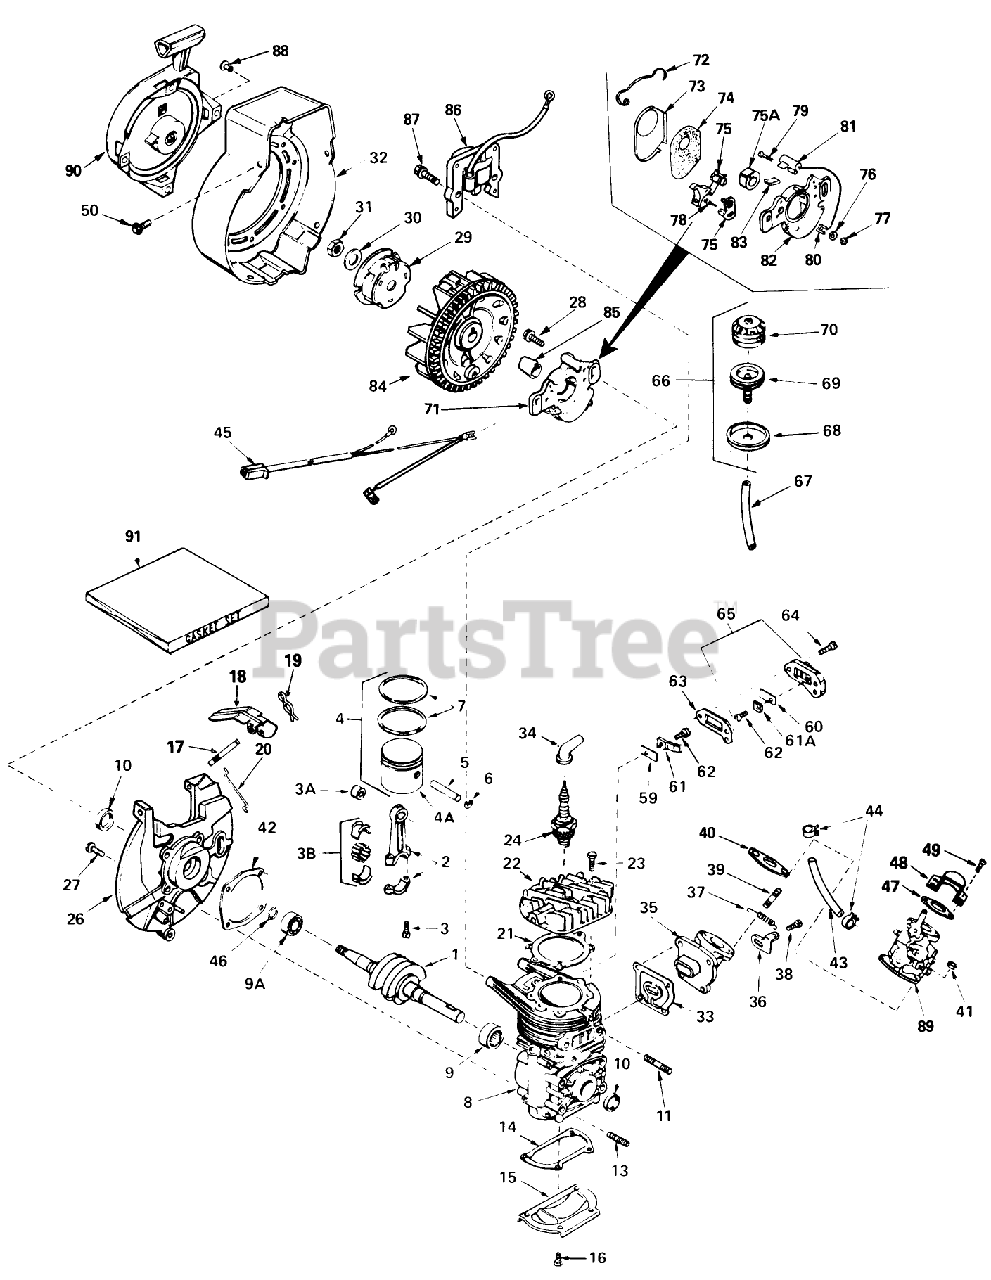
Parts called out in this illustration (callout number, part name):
1	Crankshaft
2	Rod Assembly, Connecting (Incl. #3, 3A 3B)
3	Bolt-Rod, Connecting
3A	Bearing-Cartridge
3B	Bearing Liner Set Needle
4	Piston, Pin Ring Assy. (Incl. Ref. #6 thru 9)
4A	Piston
5	Pin, Piston
6	Ring-Retaning
7	Ring Set
9	Bearing-Cartridge
9A	Bearing-Ball
10	Seal-Oil
11	Stud, Exhaust
14	Gasket, Cover
15	Plate, Cover
16	Screw (T-25, 10-24 x 1/2)
17	Shaft, Air Vane
18	Vane Assy., Air
19	Clip,Air Vane
20	Link-Governor
21	Gasket, Head
22	Head-Cylinder
23	Screw (T-30, 1/4-20 x 3/4)
24	Head Adjustment Knob
26	Base Assy., Blowerr Housing (Incl. Ref. #10 17)(used on type 1603, 1603A 1603B)
27	Screw
28	Screw, Hex Washer Hd.
29	Cup-Starter
30	Washer-Spring
31	Nut-Flywheel
32	Housing-Blower
33	Gasket, Port
34	Cover-Spark Plug
35	Elbow Assy., Adapter
36	Lever, Adjusting
37	Spring, Adjusting Lever
38	Screw
39	Stud Carburetor
40	Gasket, Carburetor
41	Locknut
42	Gasket, Shroud Base
43	Line-Fuel
44	Clamp-Line, Fuel
45	Harness, Wire
46	Ring, Retaining
47	Gasket
48	Baffle-Carburetor
49	Screw
50	Screw-Hex, Hd.
59	Reed, Compression Release
60	Reed, Compression Release
61	Plate, Reed Hold Down
61A	Plate, Reed Hold Down
62	Screw
63	Gasket, Compression Release
64	Screw
65	Cover Assy., Compression release (Incl. Nos. 60, 61A 62)
66	Primer Assy.
67	Line, Primer
68	Retainer, Primer Bulb
69	Body, Primer
70	Bulb-Primer
71	Stator Plate Assy. (incl. Nos. 107, 111 thru 118 120)
72	Spring Breaker Box
73	Cover-Dust
74	Gasket Dust
75	Breaker Assy.
75A	Cam, Breaker
76	Washer
77	DECAL
78	Breaker Screw
79	Condenser Screw
80	Terminal, Ground
81	Condenser
82	Stator Plate
83	Felt,Cam Wiper
84	FIywheel
85	SHIELD
86	Lamination Coil Assy. (Incl. No. 42)
87	Screw
88	Rivet, Pop (3/16" dia.)(Can be purchased locally)
89	Carburetor (Incl. Ref. #40)
90	Starter-Rewind
91	Gasket Set (Incl. items marked *)
